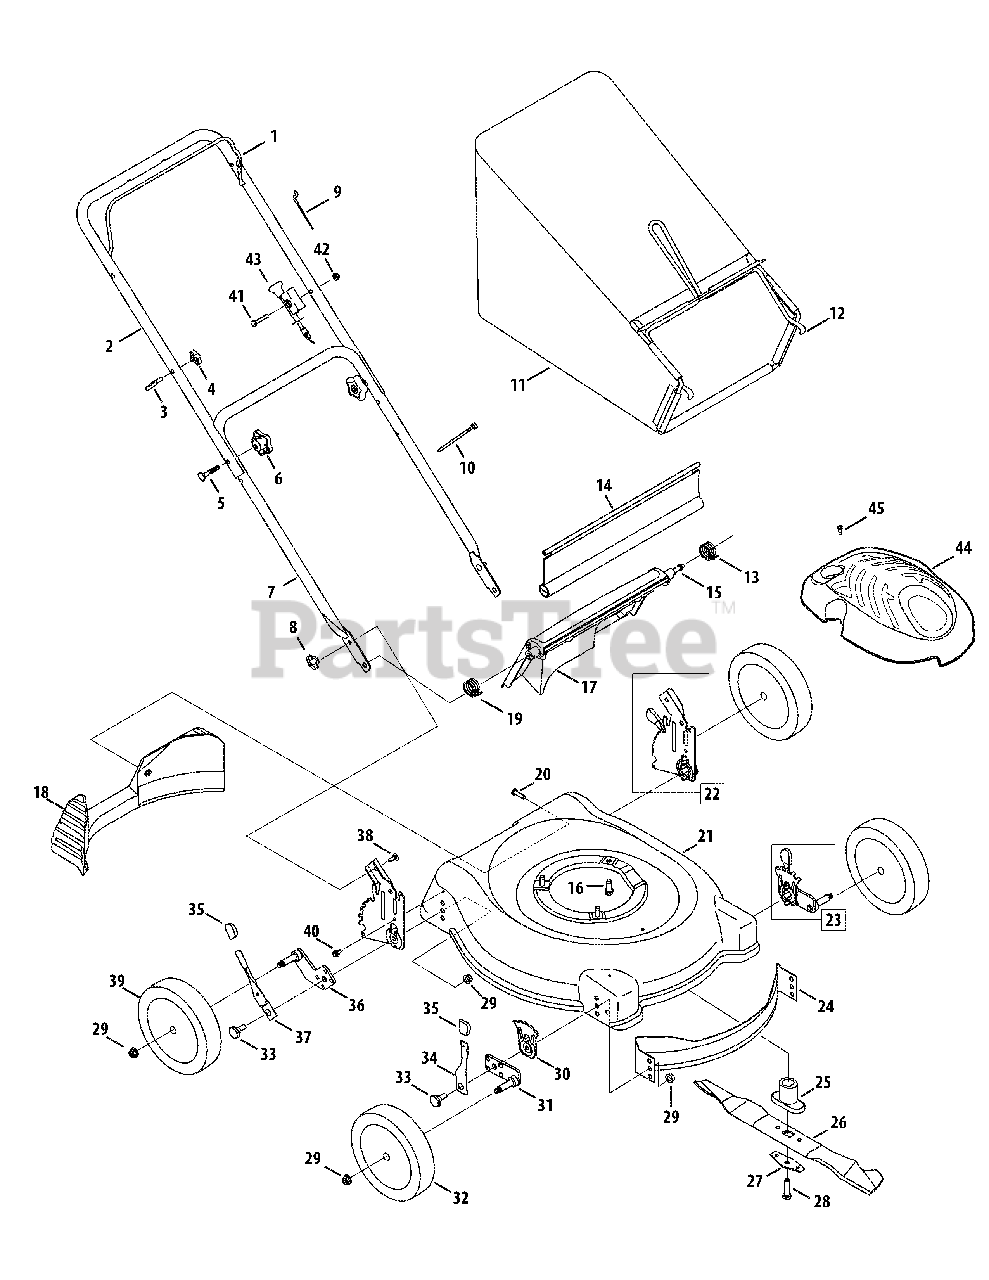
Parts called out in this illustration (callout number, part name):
3	Rope Guide
4	Wing Nut, 1/4-20
5	Carriage Bolt, 5/16-18 x 2
6	Hand Star Knob
8	Wing Nut, 1/4-20
9	Control Cable
10	Cable Tie
11	Grass Bag
13	Torsion Spring LH
14	Trailshield
15	Rear Door Pivot Rod
16	TT Screw, 3/8-16 x 1
17	Rear Discharge Door
18	Rear Baffle
19	Torsion Spring RH
20	Screw, 1/4-15 x 1.00
22	Handle Bracket Assy - RH
22	Handle Bracket Assy - LH
23	Ht. Adj. Assy. Frt - LH
23	Ht. Adj. Assy. Frt - RH
24	Front Baffle
25	Blade Adapter, #6 x 2.15 w/Star
26	Mulch Blade
27	Blade Bell Support
28	Screw, 3/8-24 x 2.50
29	Flange Lock Nut, 3/8-16
30	Height Adjustment Plate
31	Pivot Arm Assy - RH
31	Pivot Arm Assy - LH
32	Front Wheel, 7 x 1.8
33	Scr., Shldr., .500 Dia. X .385
34	Spring Lever
35	Height Adjustment Knob
36	Pivot Arm Assembly - RH
36	Pivot Arm Assembly - LH
37	Spring Lever
38	Carriage Bolt, 1/4-20
39	Rear Wheel, 8 x 1.8
40	Screw, 1/4-20 x .625
41	Screw, 1/4-20 x 1.50
42	Nut, Flglk., 1/4-20
43	Choke Cable
44	Engine Shroud
45	Screw, Mach., M4-.7
